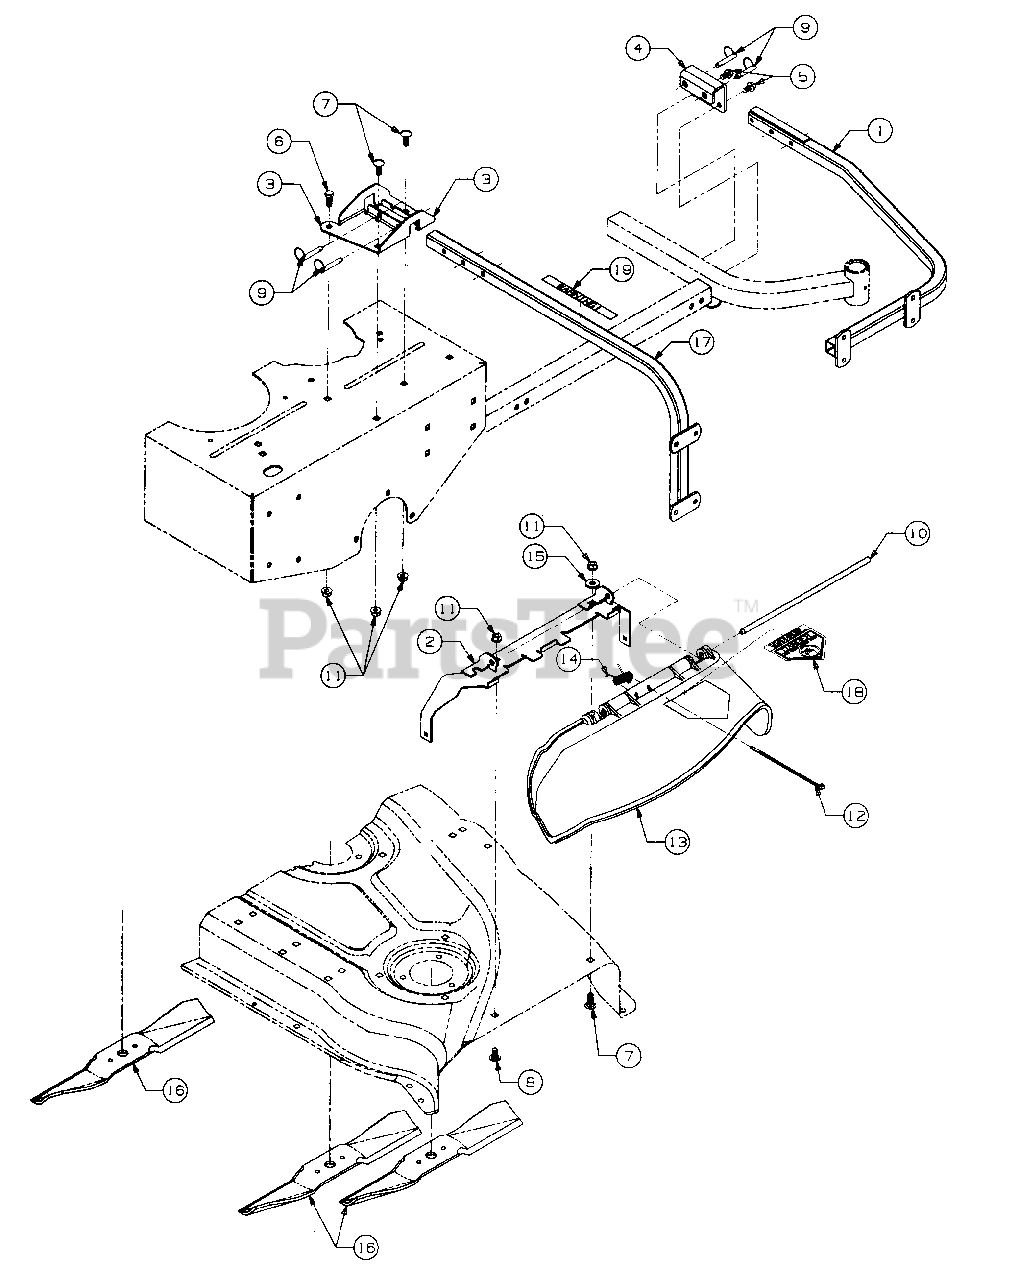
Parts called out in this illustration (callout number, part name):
1	Tube, Front Support
5	Screw, Hex Wash TT-Tapp, 5/16-18 X .62 Lg
6	Screw, Hex Cap, 3/8-16 X .875 Lg GR5
7	Bolt, Carriage, 3/8-16 X 1.0 Lg GR5
8	Bolt, Sht Nk Carriage, 3/8-16 X .75 Lg GR5
9	Pin, Clevis w/Detent Ball
10	Pin, Hinge, .375 Dia X 12.55 Lg
11	Nut, Hex Flanged Lock, 3/8-16
12	Tie, Self-Clinch Cable
13	Deflector, Chute
14	Spring, Torsion
15	Washer, Special, .378 X 1.00 X .125 Thk
16	Blade, Mower, 16.5 Lg (48" Deck)
17	Tube, Rear Support w/Graphic
18	Label, Danger
19	Graphic, Catcher Warning
